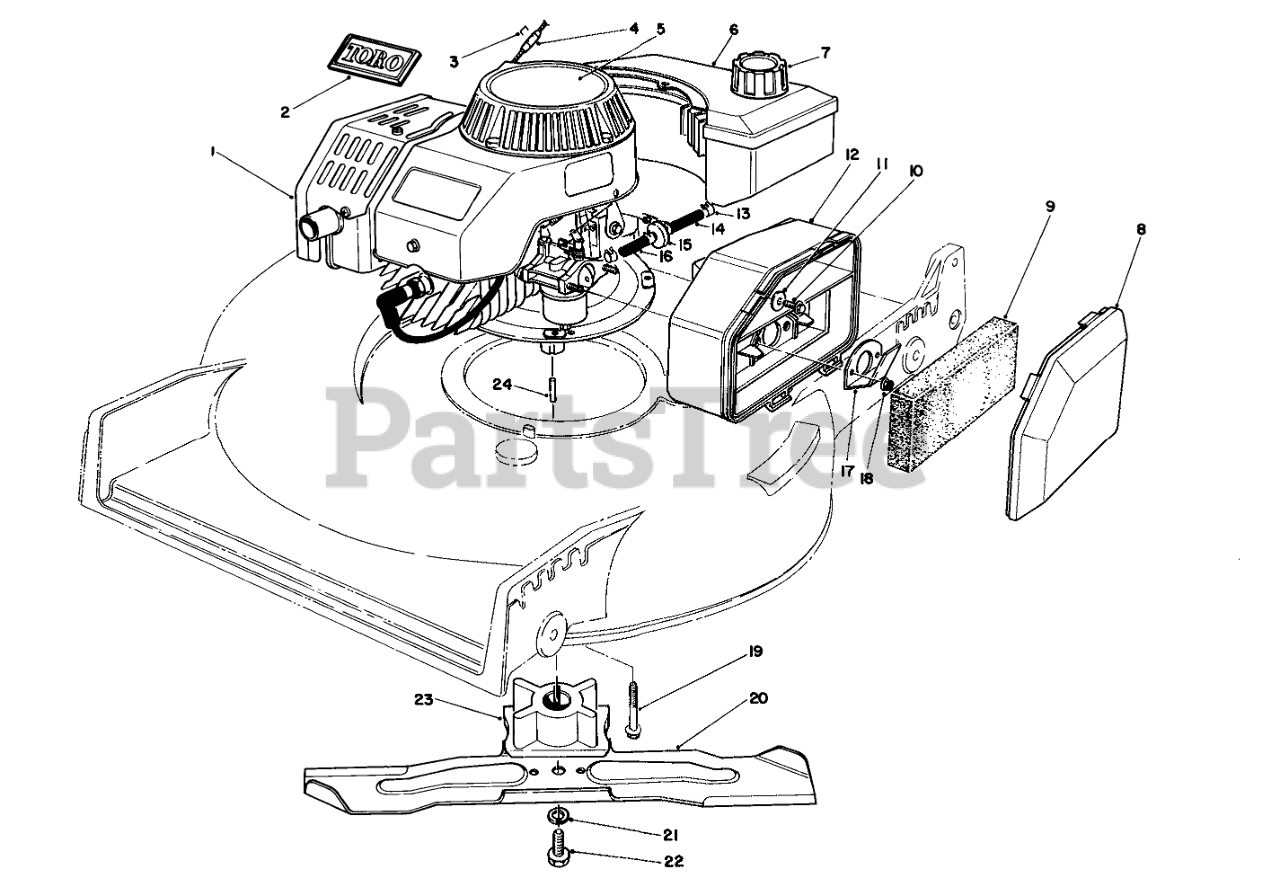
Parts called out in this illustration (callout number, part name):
1	Engine
2	TORO LOGO PLT
3	Staple
4	STOP-ROPE
5	DECAL
6	Gas Tank Assembly
7	GAS CAP ASM
8	AIR CLEANER COVER
9	FILTER
10	SCREW-HH
11	WASHER-FLAT
12	AIR CLEANER
13	CLAMP-FUEL LINE
14	HOSE-FUEL
15	FILTER-FUEL
16	HOSE-FUEL
17	SPIT BACK DEFLECTOR
18	NUT-LOCK
19	SCREW-HHF
20	BLADE-21in
21	WASHER-LOCK
22	SCREW-BLADE
23	Retainer Blade
24	KEY-SQUARE
